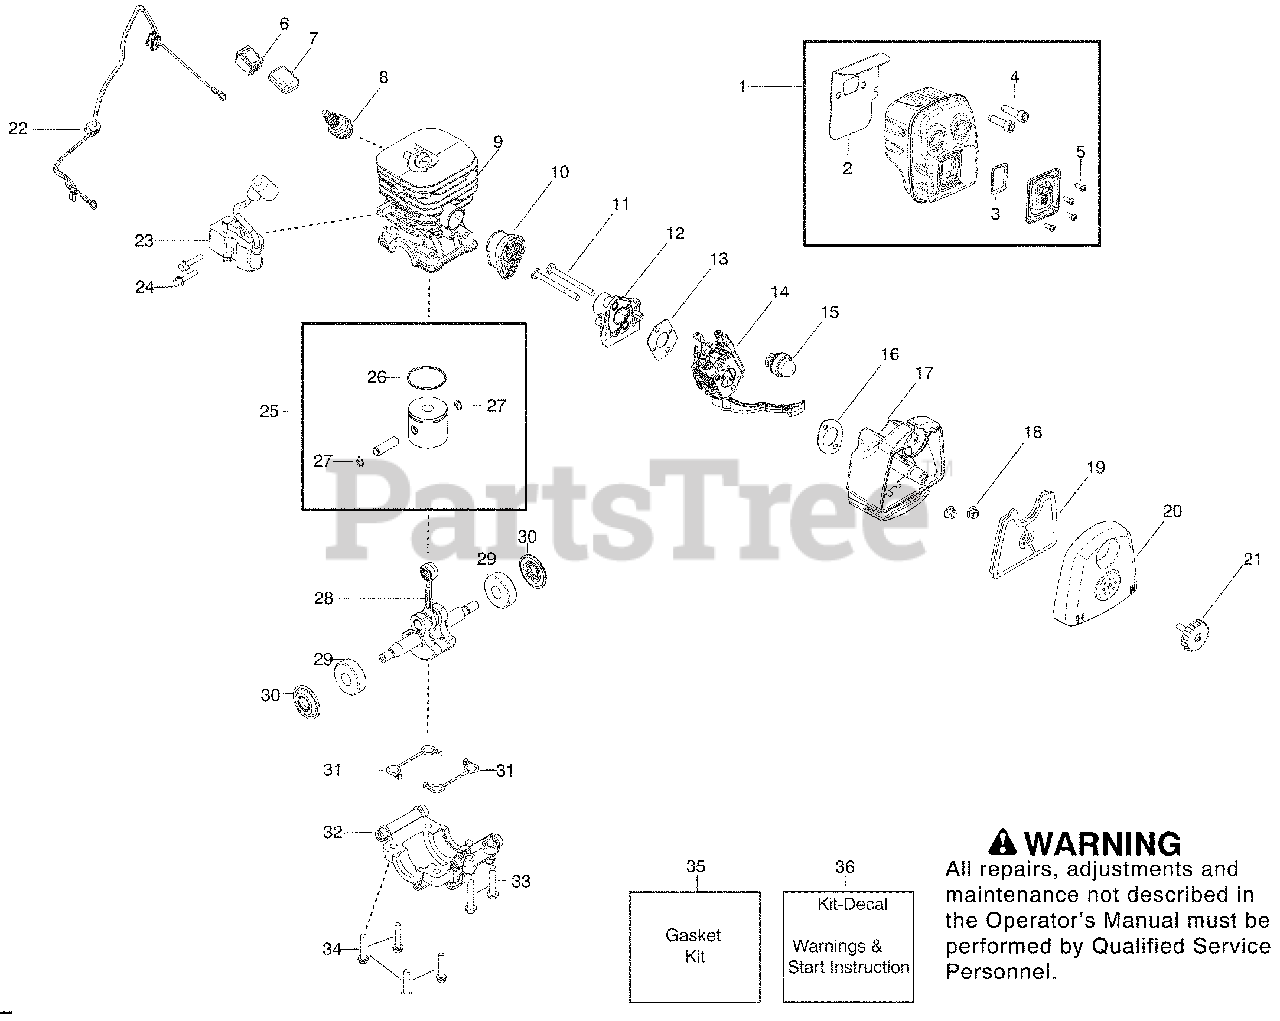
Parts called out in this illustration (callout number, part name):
1	Assy - Muffler
2	Gasket - Muffler (kit)
3	Kit - Spark Screen
4	Bolt - Muffler
5	Screw
7	Protector - Switch
8	Accy - Spark Plug (RCJ6-Y)
9	Cylinder - Chrome
10	Boot - Carb.
12	Plate - Carb.
13	Gasket - Carb. (kit)
14	Kit - Carb. (X5055)
15	Bulb - Purge
16	Gasket - Airbox (kit)
17	Base - Airbox
18	Nut - Carb screw
19	Filter - Air
20	Cover - Airbox
21	Assy - Airbox Knob
22	Assy - Leadwire
23	Module - Ignition
25	Kit – Piston
26	Ring - Piston
27	Retainer - Piston pin
28	Kit - Crankshaft
30	Kit - Crankshaft seal
31	Seal - Cylinder (kit)
32	Cap - Bearing
35	Kit - Gasket
36	Kit - Decal
